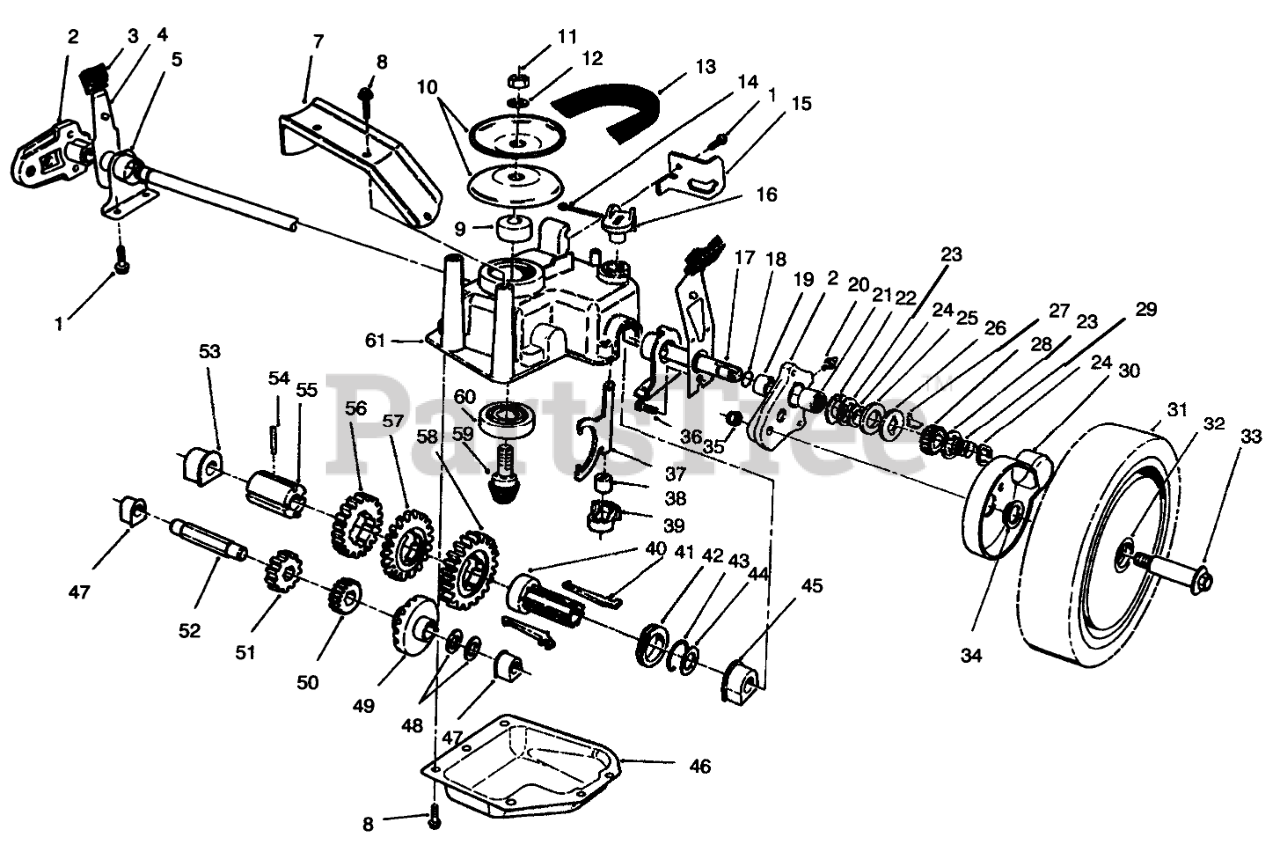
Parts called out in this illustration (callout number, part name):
1	SCREW-HWHTF
2	Pivot Arm Assembly (Incl. Ref. #19-21)
3	KNOB-ARM
4	SPRING ARM ASM
5	CAP-END
7	Bracket-BeltGuide
8	SCREW-HWHTF
9	SPACER
10	Pulley Half
11	NUT-HEX
12	WASHER-FLAT
13	V-BELT
14	PIN-COTTER
15	RETAINER-CABLE
16	LEVER-SHIFT
17	SHAFT-OUTPUT
18	O-RING
19	BUSHING
20	FITTING-GREASE
21	BEARING-ROLLER
22	WASHER-ARM, PIVOT
23	WASHER-THRUST, KEYED
24	RING-CLIP, LOCKING
25	RING-FRICTION
26	WASHER-CLUTCH
27	KEY-ROCKING, LH
28	GEAR-PINION
29	SPRING-COMPRESSION
30	COVER-WHEEL
31	Wheel Tire & Gear Assy. (Incl. Ref. #32)
32	BUSHING
33	WHEEL BOLT
34	SPACER-COVER, WHEEL
35	NUT-LOCK
36	SCREW-HSH, THREAD FORMING
37	YOKE-SHIFT
38	BUSHING-YOKE
39	RETAINER-FORK, SHIFT
40	SLEEVE-KEY, SHIFT
41	KEY-SHIFT
42	COLLAR-SHIFT
43	CLIP-SPRING
44	WASHER-PLAIN
45	BUSHING-OUTPUT
46	Cover-Gearcase
47	BUSHING
48	WASHER-THRUST
49	Gear-Bevel
50	PINION-20T
51	PINION-25T
52	SHAFT-INTERMEDIATE
53	BUSHING
54	PIN-SPRING
55	SLEEVE-GEAR
56	GEAR-39T
57	GEAR-44T
58	GEAR-49T
59	Gear-Pinion
60	BEARING-BALL
61	CASE-GEAR, UPPER
